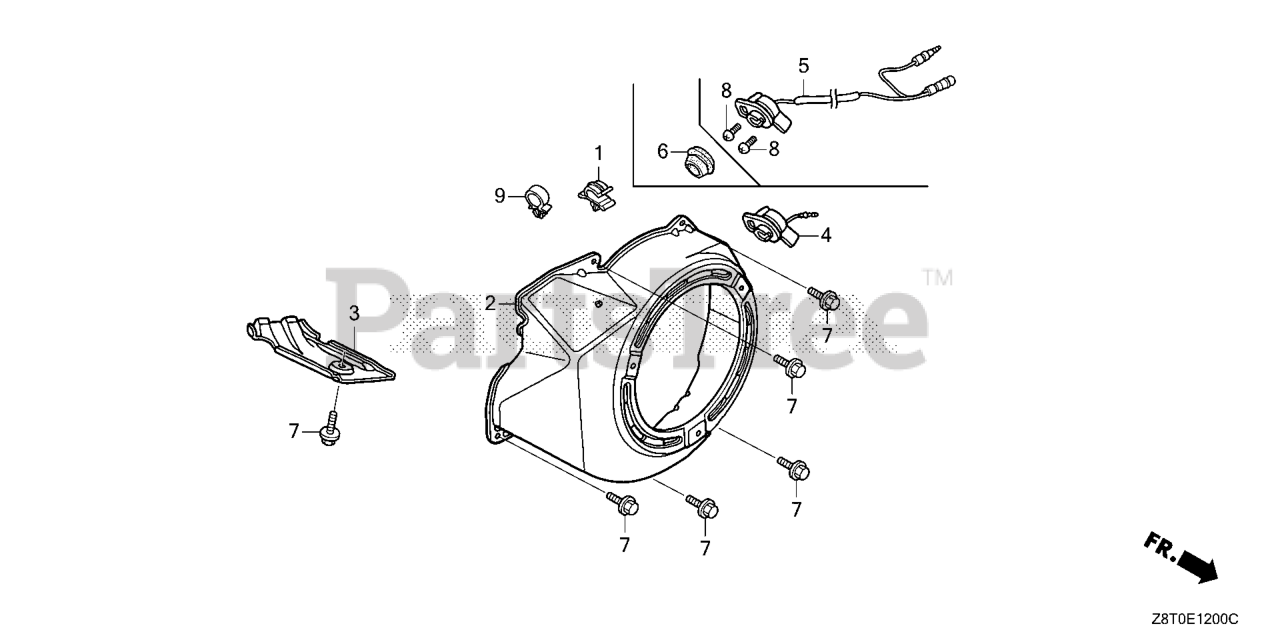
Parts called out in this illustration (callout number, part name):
1	CLIP, TUBE
2	COVER, FAN *R280* (POWER RED)
2	COVER, FAN *NH1* (BLACK)
5	SWITCH ASSY., ENGINE STOP
7	BOLT, FLANGE (6X12) (CT200)
8	SCREW, TAPPING (3X6) (PO)
